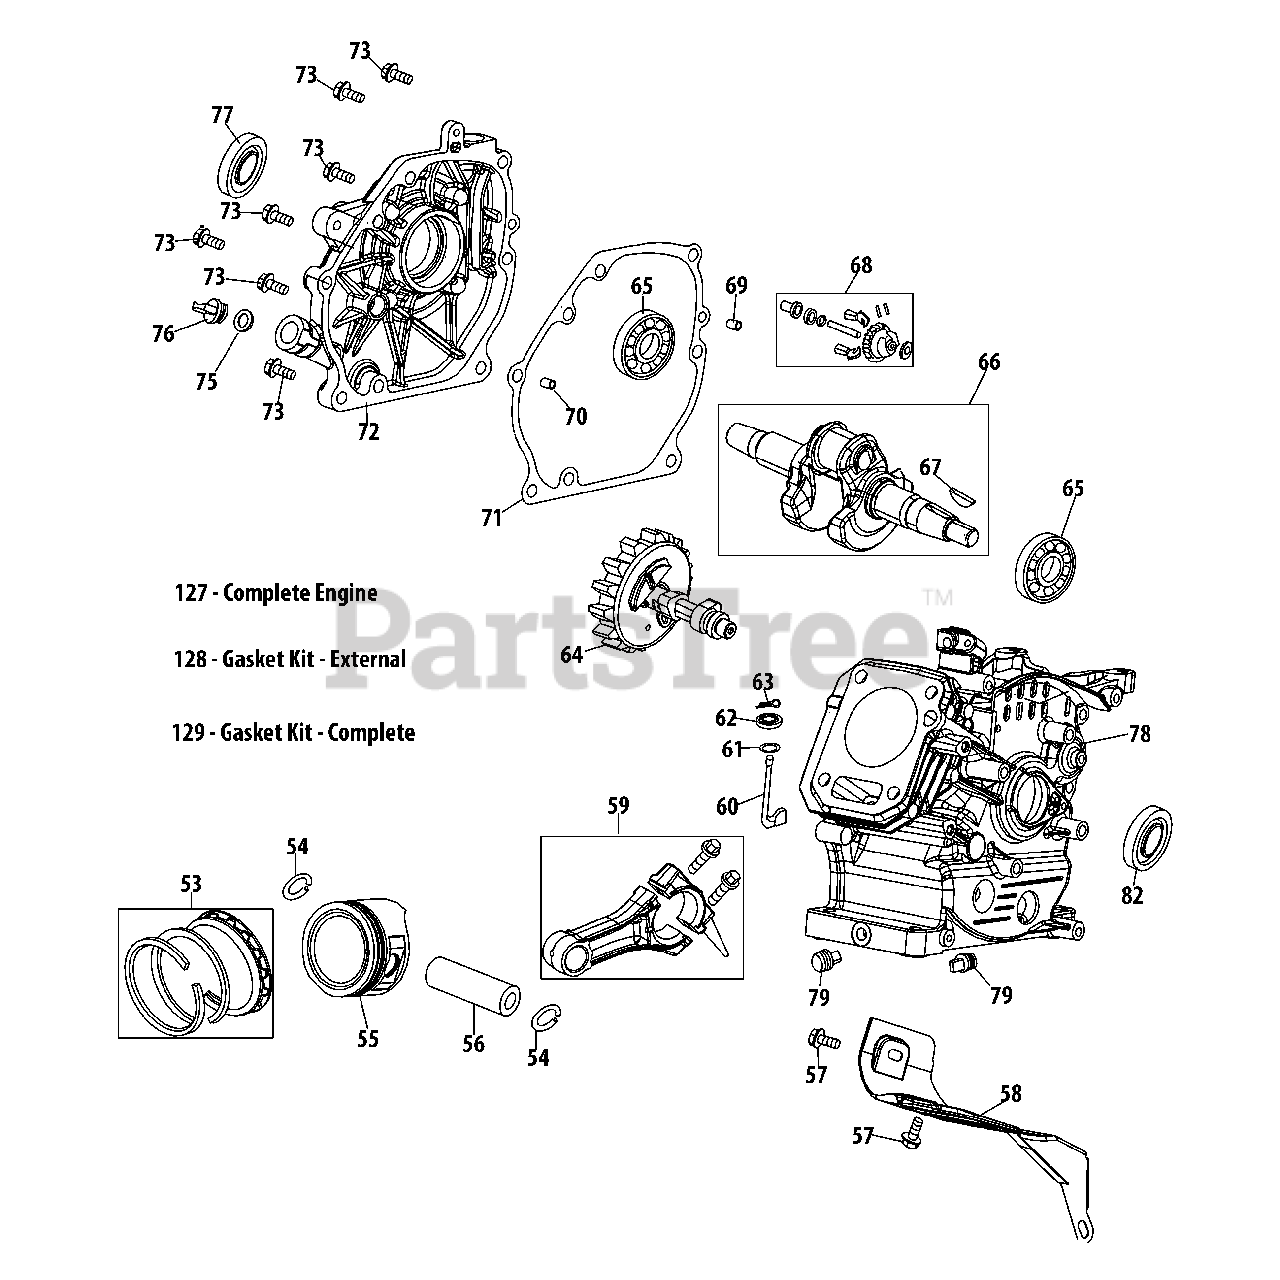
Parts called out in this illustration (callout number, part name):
53	Piston Ring Set
54	Piston Pin Snap Ring
56	Piston Pin
57	Bolt M6×12
58	Air Shield
59	Connecting Rod Assembly
60	Governor Shaft
61	Washer - 5.2 X 1.9
62	Governor Seal
63	Cotter Pin
64	Camshaft Assembly
65	Radial Ball Bearing, 6205
66	Crankshaft Service Kit
67	Woodruff Key
68	Governor Gear/Shaft Assembly
69	Dowel Pin 7×14
70	Dowel Pin 9×14
71	Crankcase Cover Gasket
72	Crankcase Cover
72	Crankcase Cover Service Kit
73	Bolt M8×32
75	O-Ring 15.8 X 2.5
77	Oil Seal, 25×41.25×6
78	Crankcase Service Kit
78	Shortblock Assembly
79	Oil Drain Plug
127	Complete Engine
128	Gasket Kit - External
129	Gasket Kit - Complete
